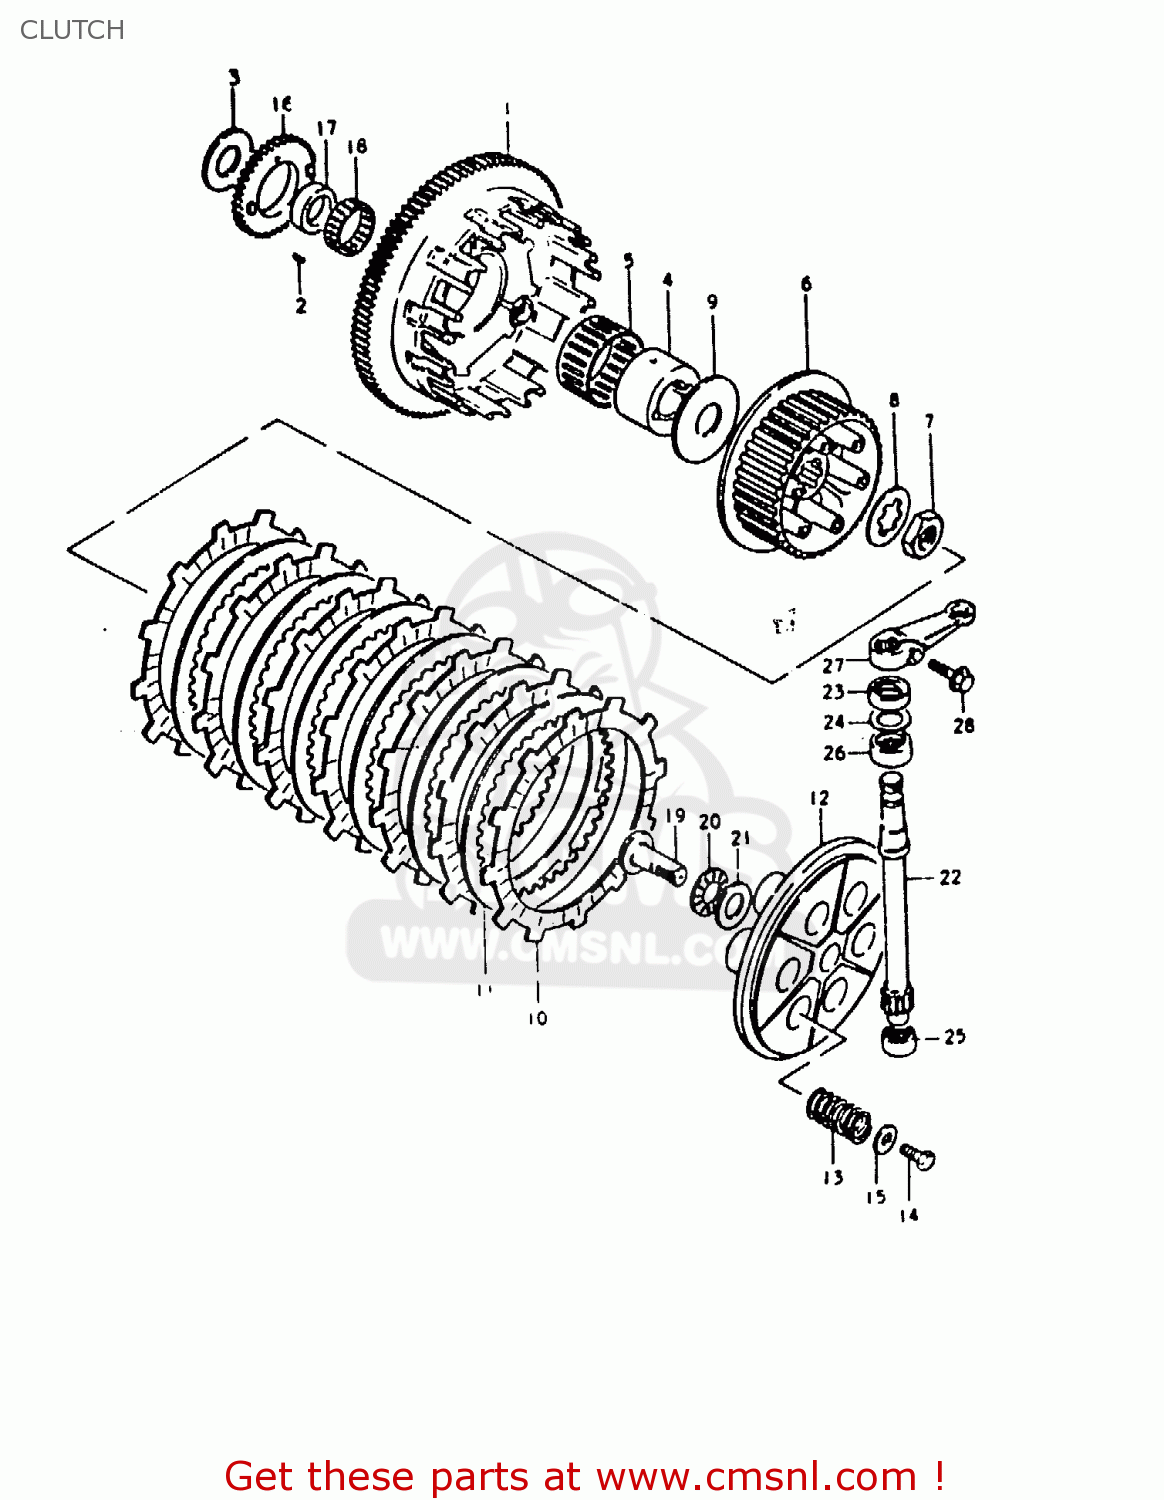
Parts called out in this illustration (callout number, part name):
1	GEAR ASSEMBLY,PRIMARY DRIVE
2	CUSHION,PRIMARY DRIVEN GEAR
3	WASHER
4	SPACER,PRIMARY DRIVEN
5	BEARING
6	HUB,CLUTCH SLEEVE
7	NUT
8	WASHER,LOCK
9	WASHER(25X66X3.5)
10	PLATE,CLUTCH DRIVE (MCA)
11	PLATE,CLUTCH DRIVEN (NAS)
12	DISC,CLUTCH PRESSURE
13	SPRING
14	BOLT, UPPER
15	WASHER
16	GEAR,OIL PUMP DRIVE
17	SPACER,OIL PUMP DRIVE GEAR
18	BEARING(36X40X10)
19	RACK,CLUTCH RELEASE
20	BEARING(15X28X2)
21	WASHER
22	PINION,CLUTCH RELEASE
23	OIL SEAL
24	WASHER (14.2X22X1)
25	BEARING(12X19X12)
26	BEARING(15X22X12)
27	ARM,CLUTCH RELEASE
28	BOLT
